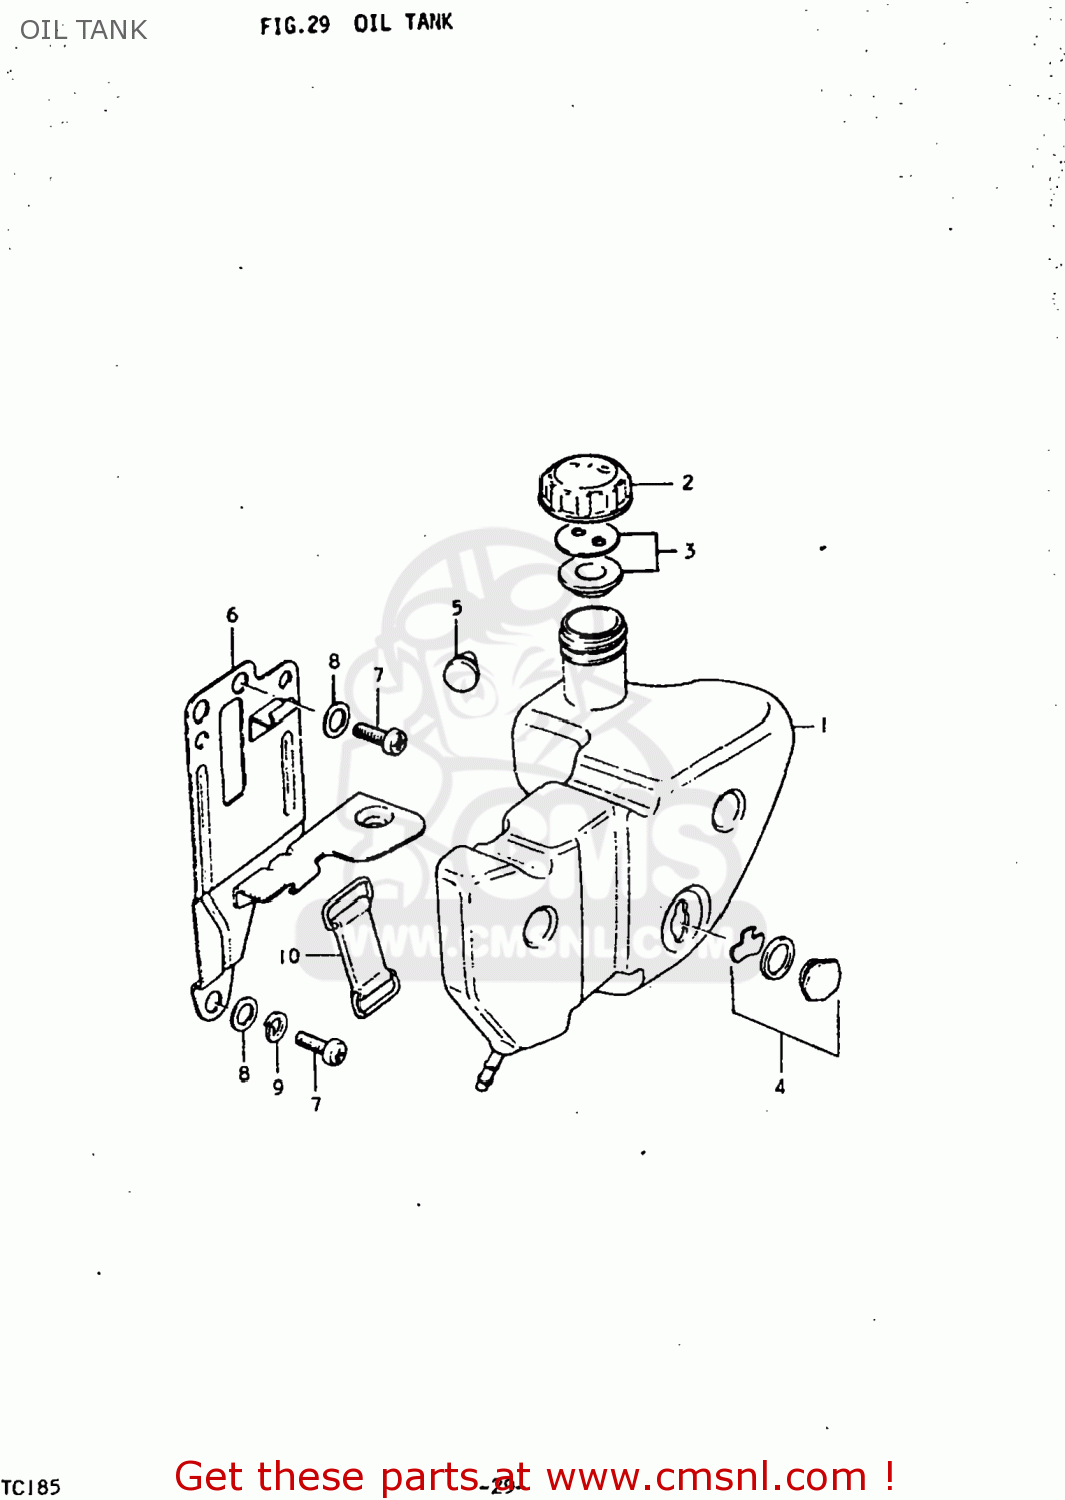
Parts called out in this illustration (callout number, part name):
1	TANK,OIL
2	CAP,OIL TANK
3	LENS,OIL LEVEL INSPECTION
4	LENS,OIL LEVEL INSPECTION
5	CUSHION
7	SCREW 6X12
8	WASHER
9	LOCK WASHER
10	BAND
